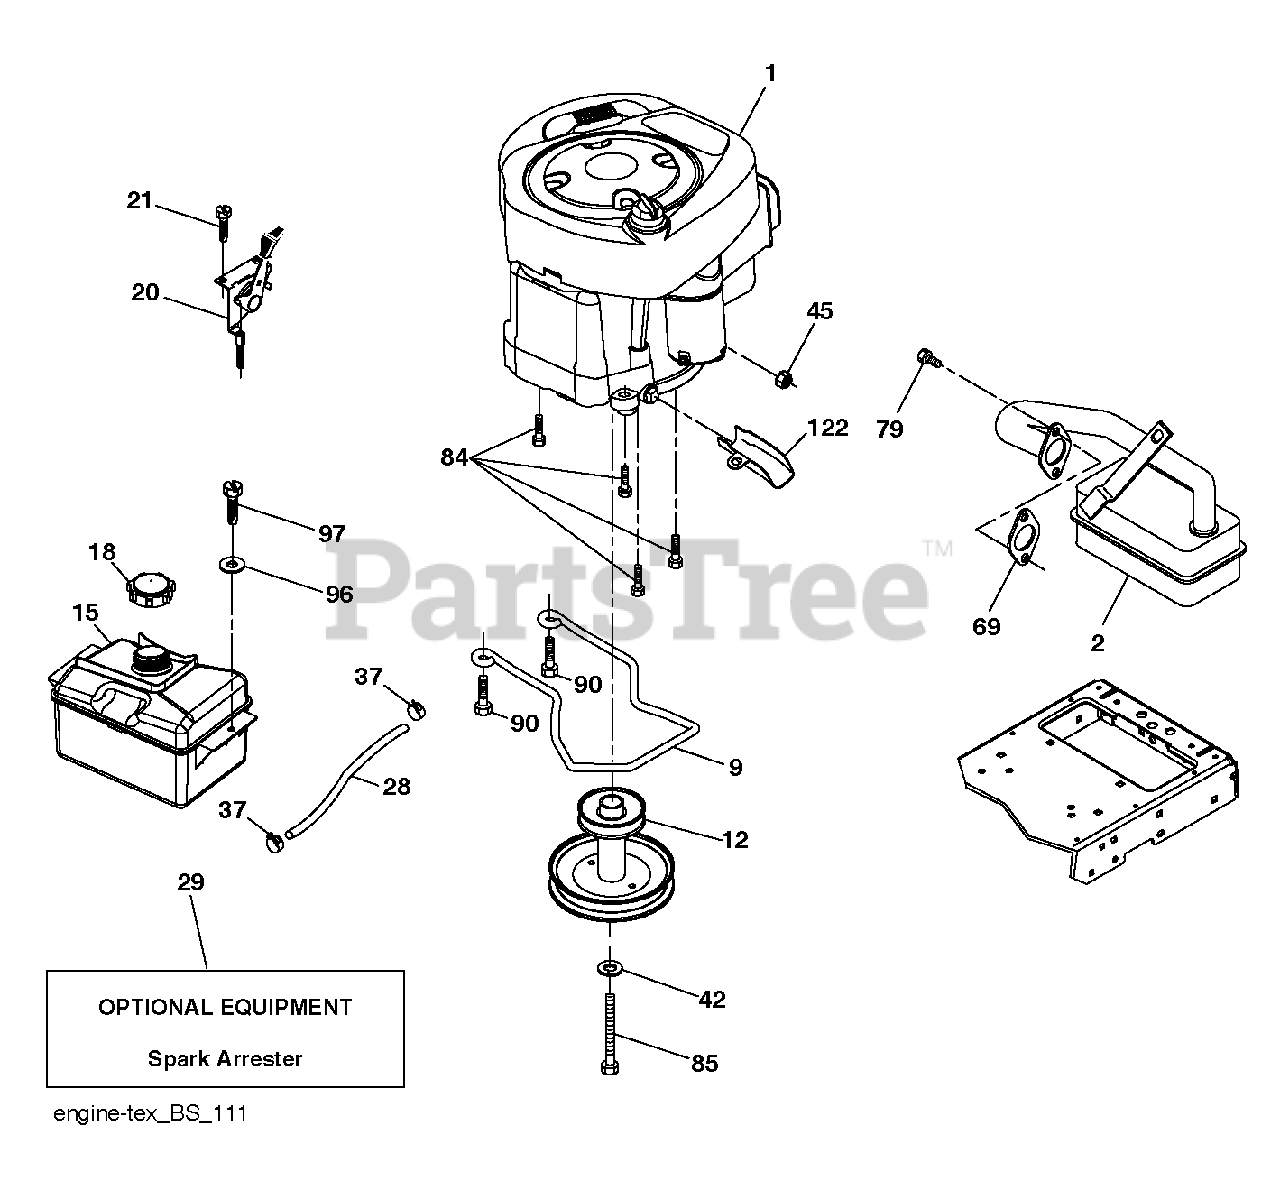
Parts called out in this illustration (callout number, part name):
2	MUFFLER.SINGLE.CYL.KOHL/B&S
9	KEEPER.BELT.ENG.3.25"2BOLT.PNT
12	PULLEY.ENGINE
15	RP TANK FUEL FRT 1.5 GAL
18	CAP ASM.FUEL.2.25"FR.
20	THROTTLE.COBRA.21".RSTART.BLK
21	SCREW.#10 X 0.750.BOS
28	LINE.FUEL.20
29	KIT.SPARK ARRESTOR 794945 B&S
37	HOSE CLAMP
42	WASHER 7/16 LOCK
45	NUT
69	GASKET.EXHAUST.KOHLER
79	SCREW.SOCKET HD.5/16-1
84	SCREW.3/8-16
85	BOLT.HEX.7/16-20X4.GR5.1.5BLUE
90	SCREW 3/8-16X1
97	SCREW HEXWSHR 1/4-20X3/4
122	EXTENSION DRAIN OIL
